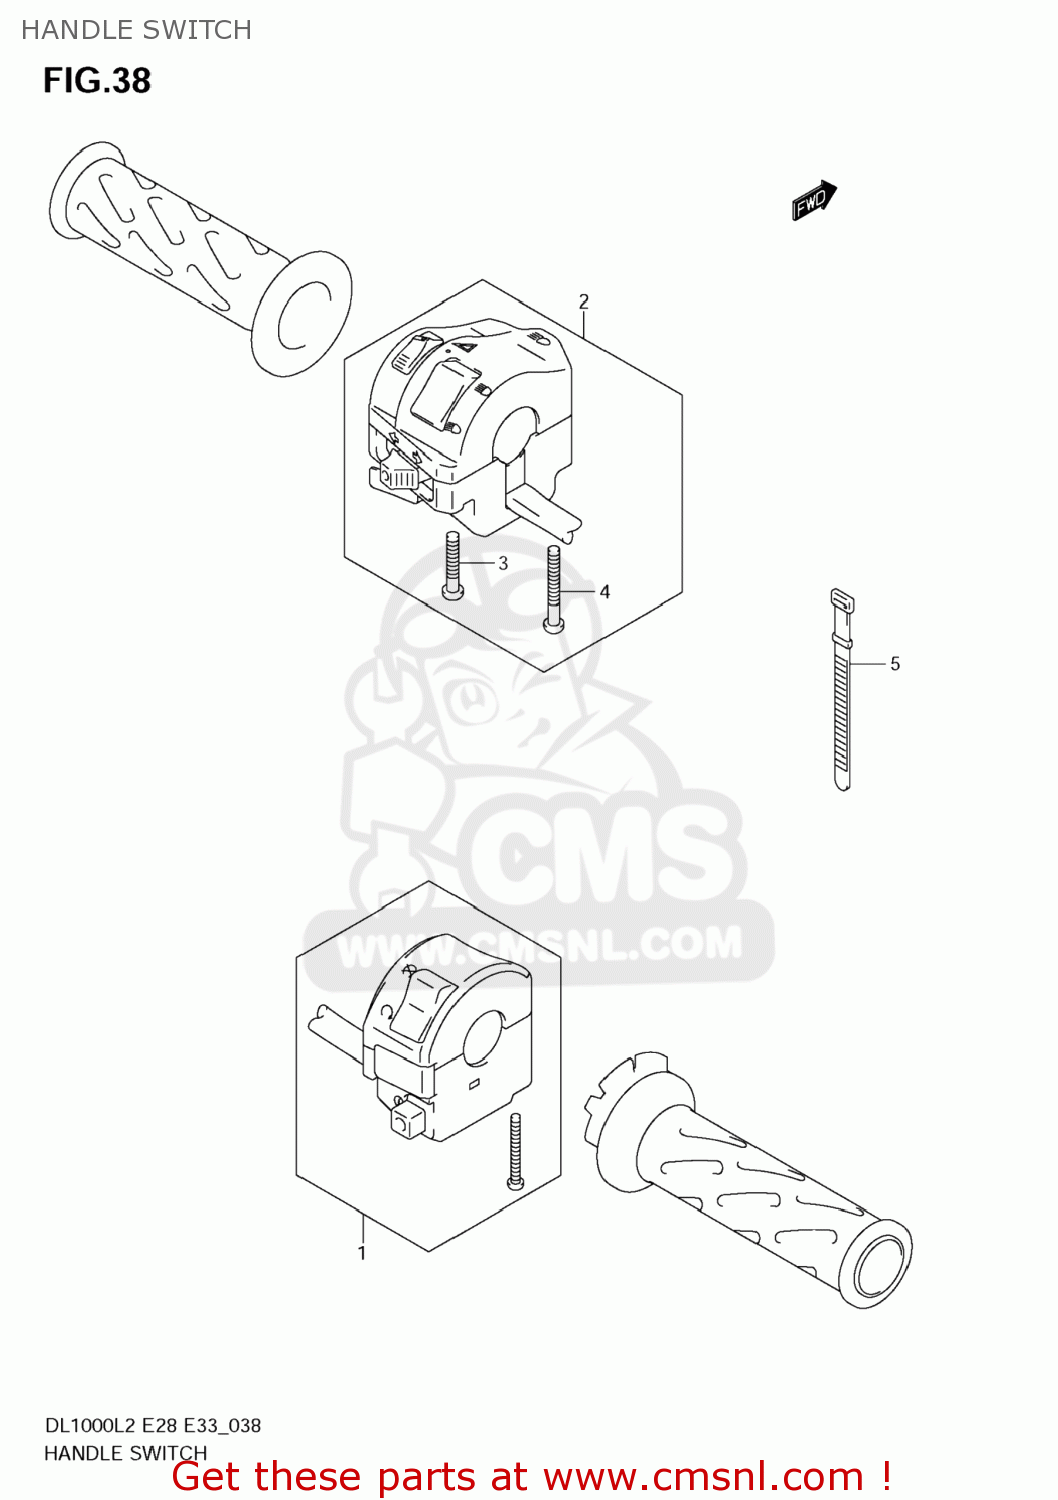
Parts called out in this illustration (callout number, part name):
1	SWITCH ASSY,HANDLE,R
2	SWITCH ASSY,HANDLE,L
3	SCREW
4	SCREW
5	CLAMP(L:120)
